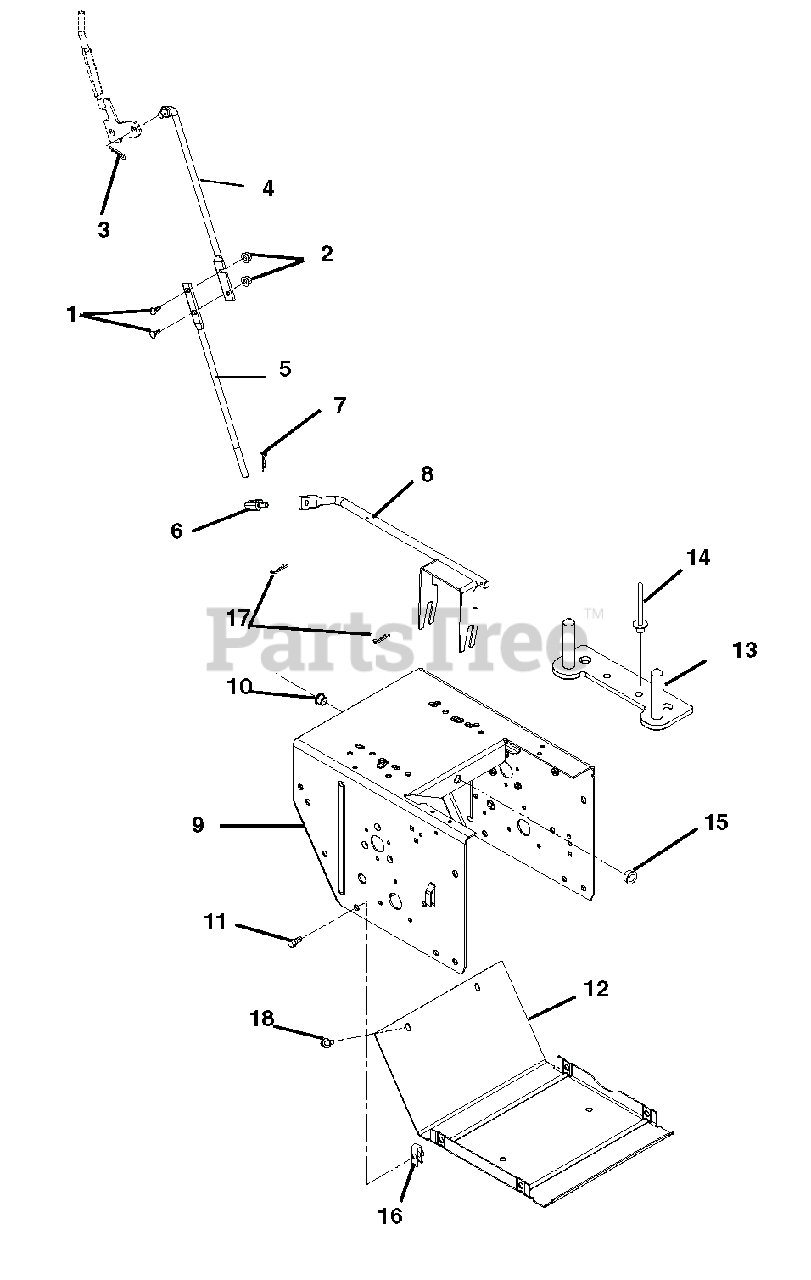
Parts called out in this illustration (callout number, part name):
1	@BLT-RDHDSQNK .25-20X.75 G5YZ
2	@NUT-LK-TOP-FLG .25-20 YWZC
3	PIN-HAIR, ENDRIES #25 YWZC
4	ROD, SHIFT-UPPER
5	ROD, SHIFT-LOWER
6	PIVOT,SHIFT ROD .375-16(TRUNN)
7	PIN-HAIR, ENDRIES #25 YWZC
8	ARM, SHIFT-WELDMENT
9	FRAME, MAIN
10	BUSHING, POLYLINER-.50 SPLIT
11	BLT-HEX .25-20X.75 HWH YZ GR5
12	COVER, BOTTOM
13	STRAP, ENGINE BOLT-LARGE BRIGG
14	RVT-POP .187 YZ
15	BUSHING, POLYLINER-.50 SNAPIN
16	NUT-RTNR .25-20X.56
17	CLIP, SPRING
18	SCR-TAP .25-20X.50 HWH TR YWZ
